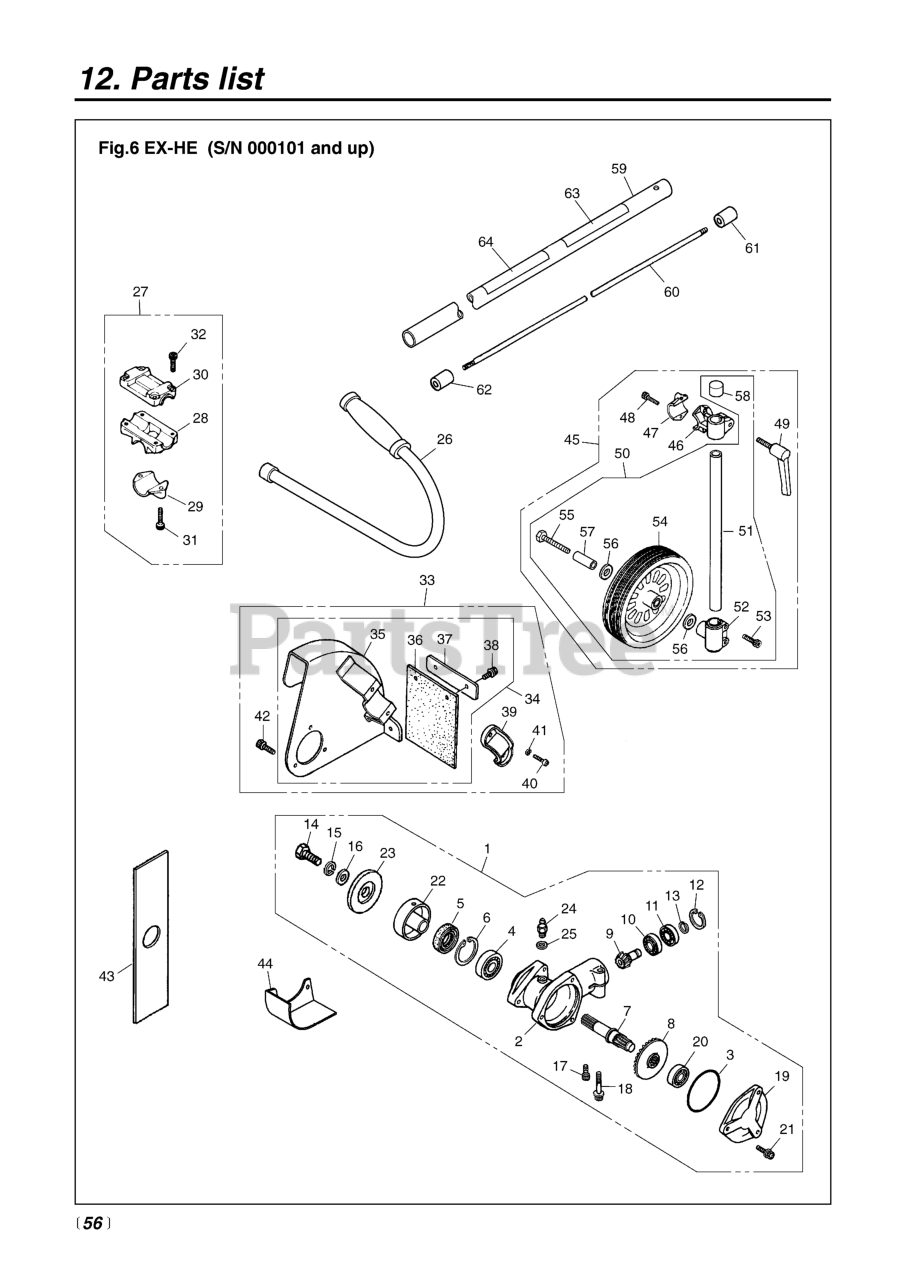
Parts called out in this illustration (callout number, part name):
3	O-RING
5	SEAL, OIL
6	RING, SNAP, M32 x 1.2
7	SHAFT, GEAR
8	GEAR
9	PINION
10	BEARING (RPLS T3403-13530)
11	BEARING (RPLS T3300-13531)
12	RING, SNAP, M24 x 1.2
13	RING, SNAP (RPLS T3300-13330)
14	BOLT, LH
15	WASHER (RPLS 3180-13270)
16	WASHER, M8 x 2.3 (RPLS -20823)
17	BOLT, M5 x 12
18	BOLT, M6 x 1.35
19	COVER
20	BEARING (RPLS T3403-13510)
21	BOLT
22	HOLDER (A)
23	HOLDER (B)
24	FITTING, GREASE
25	WASHER, M6 X .8
26	HANDLE, J
27	BRACKET ASSY (REPLACES -14100)
29	CAP, LOWER
30	CAP, UPPER (RPLS -14191)
31	BOLT, M5 X 22
32	BOLT, M5 X 25
34	COMP. GUARD
35	GUARD (RPLS 6367-24110)
36	PLATE (RUBBER)
37	PLATE (REPLACES -24130)
38	BOLT, M5 X 12
40	BOLT, M6 X 18
41	WASHER, M6 X 15
42	BOLT
43	BLADE, EDGER (RPLS 147315)
44	COVER (CAN USE 6367-96110)
45	WHEEL ASSY COMP (RPLS -25000)
46	BRACKET
47	CAP, LOWER
48	BOLT, M5 X 22
49	LEVER
50	WHEEL ASSY (RPLS -25100)
51	PIPE
53	BOLT, M6 X 25
54	WHEEL
55	BOLT (REPLACES -81060)
56	WASHER, M10 x 1.6
57	SPACER, PIPE
58	CAP
59	PIPE COMPLETE
60	SHAFT
61	JOINT, SHAFT (RPLS -12240)
62	SPACER
63	NAMEPLATE
64	PLATE, CAUTION
